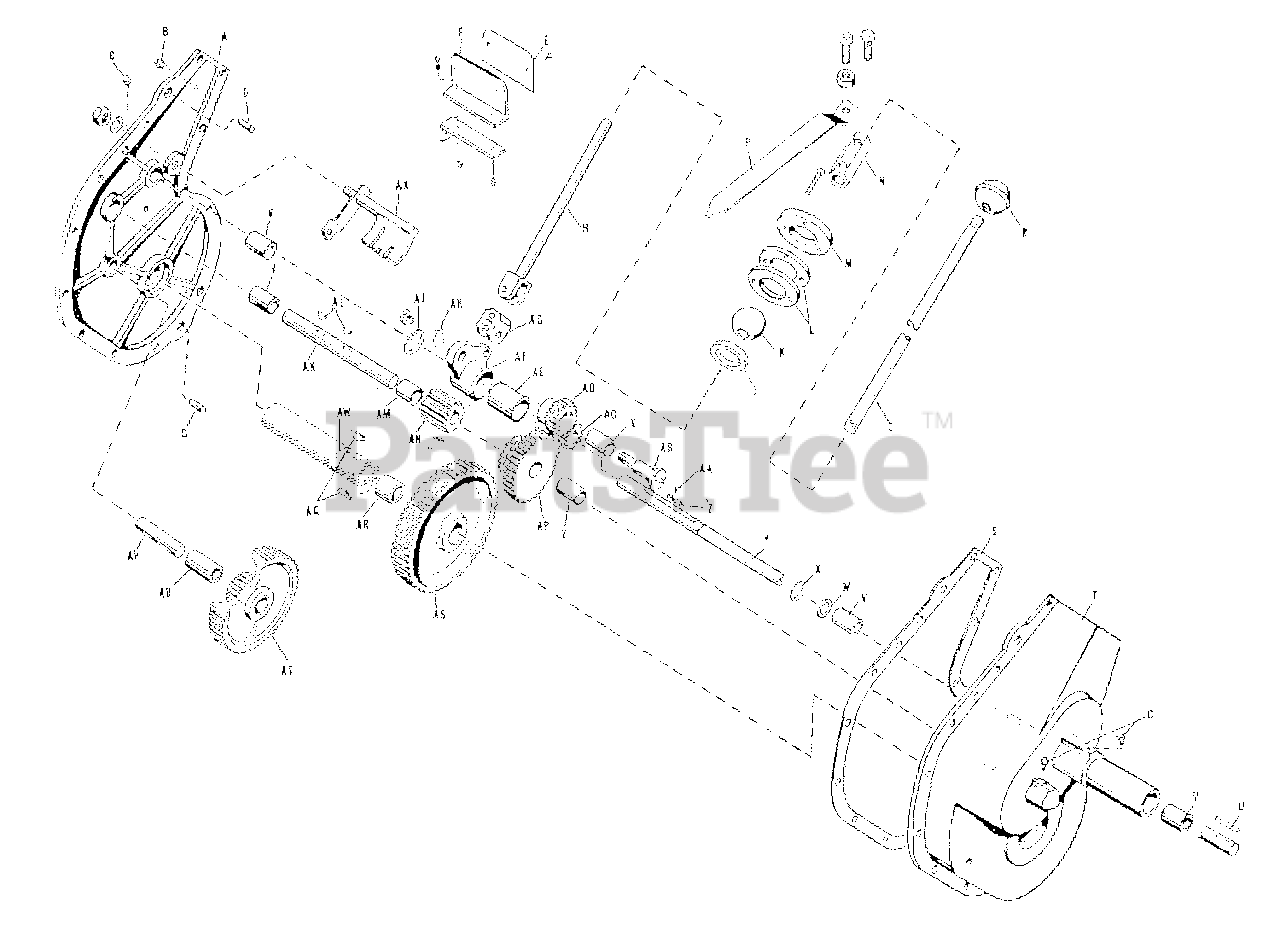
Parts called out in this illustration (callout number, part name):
A	COVER, Gear Case
B	GREASE FITTING, Alemite #1641
C	GREASE FITTING, Alemite #1909
D	PIN, Dowel
E	PLATE, Serial and Shift Instruction
F	BRACKET, Shift Instruction Plate
G	HOLDER, Shift Instruction Plate, Bracket
H	CLEVIS ASSEMBLY, Pitman
J	WASHER, Shift Ball
K	BALL, Gear Shift
L	SPACER, Shift Ball
M	RETAINER, Shift Ball
N	COUPLING, Gear Shift Handle
P	POINTER, Shifter
Q	EXTENSION, Gear Shift Handle
R	BALL, Shift Lever
S	GASKET, Gear Case
T	CASE, Gear
U	KEY, Transmission Pulley
W	WASHER, Spacer
X	RING, Retaining
Y	SHAFT, Transmission Pulley
Z	KEY, Transmission Slide
AA	PLATE, Slide Key Lock
AB	PIN, Rocker Arm Pinion
AC	GEAR, Transmission Slide
AD	PINION, Rocker Arm with Bearing
AE	BEARING, Rocker Arm
AF	ARM, Rocker Assembly
AG	PITMAN, Gear Shift
AH	PLATE, Lock
AJ	RING, Retaining
AK	SHAFT, Transmission Pinion
AL	KEY, Woodruff, 5/32 x 5/8"
AM	SPACER, Transmission Pinion Shaft
AN	GEAR, "High"
AP	GEAR ASSEMBLY, Cluster
AQ	KEY, Drive Gear
AS	GEAR, Drive
AT	GEAR ASSEMBLY, Cluster
AU	BUSHING, Intermediate, 5/8" x 3/4" x 1-7/16"
AV	SPINDLE, Intermediate
AW	RING, Snap
AX	GUIDE ASSEMBLY, Shift
